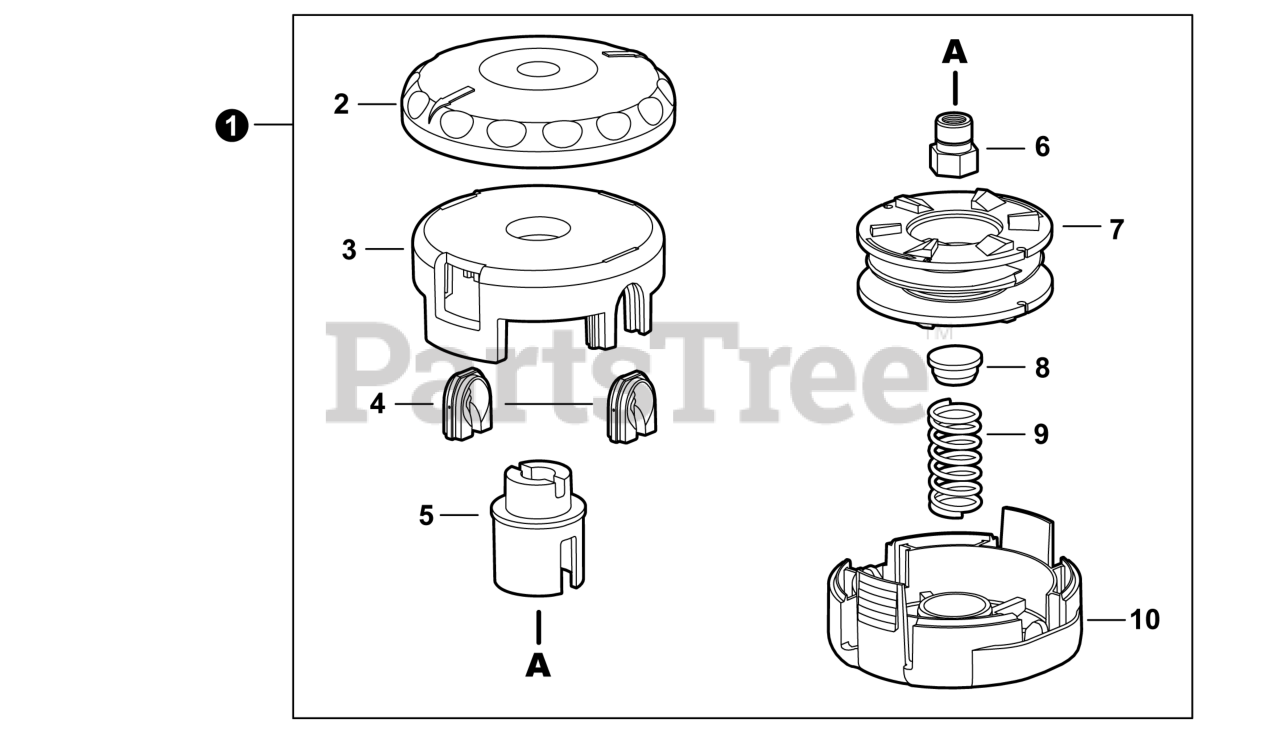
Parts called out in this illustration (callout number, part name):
1	TRIMMER HEAD, SPEED-FEED® 375
3	HOUSING, SPOOL
5	HUB, SPOOL
6	BUSHING M10x1.25 LH GOLD
7	SPOOL LH
8	CAP, SPRING
9	SPRING, GOLD
10	COVER, SPOOL
